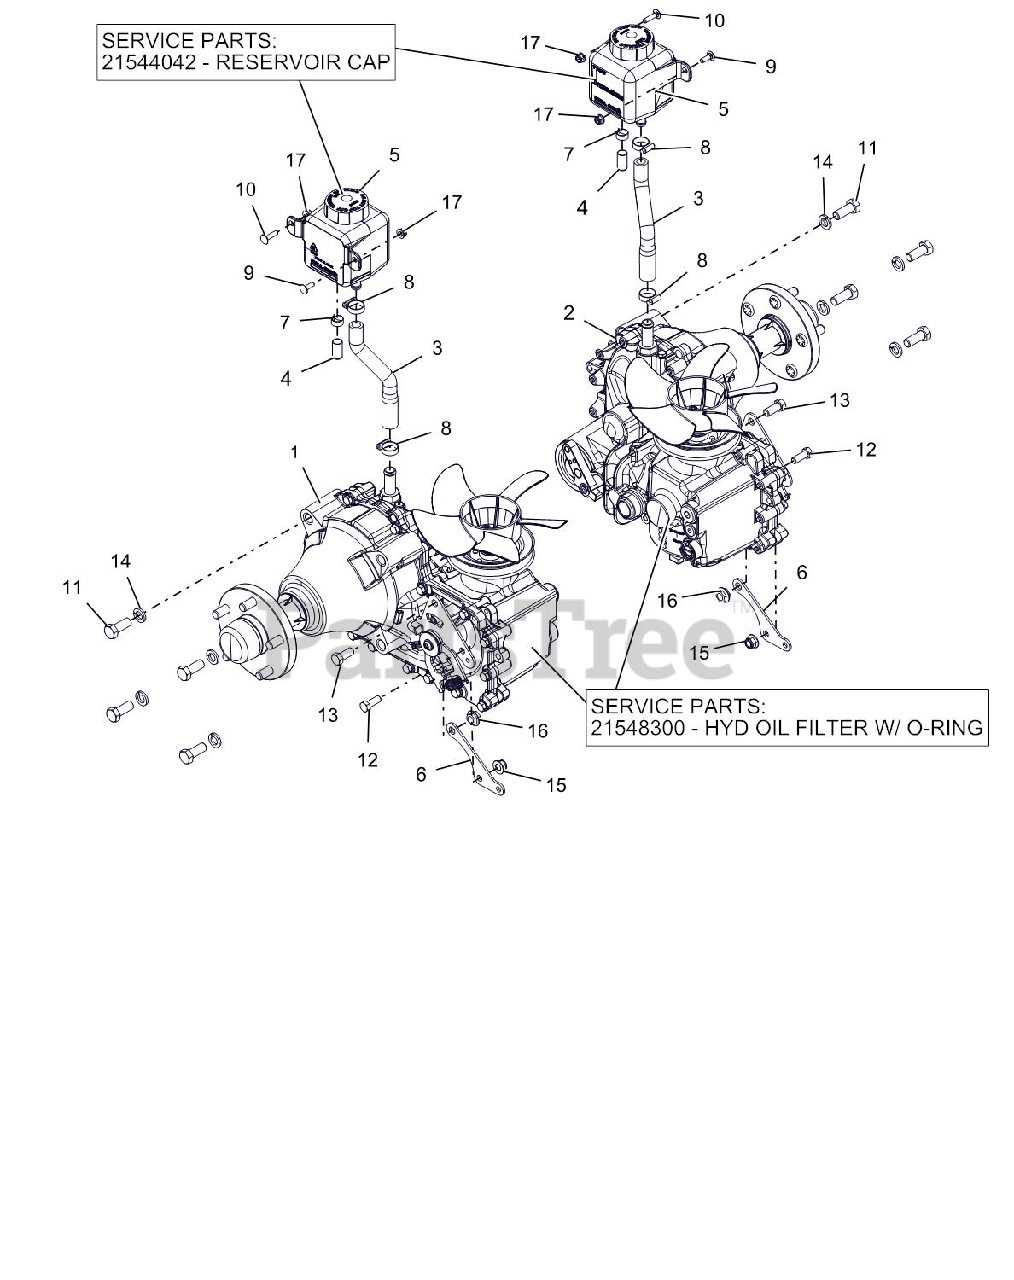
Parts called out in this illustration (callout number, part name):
1	TRANS, RH HG ZT-5400
2	TRANS, LH HG ZT-5400
3	HOSE,PT200/400 TRANS OVERFLOW
4	CAP, .50 BARBED FITTING
5	CAP, HYDRO RESERVOIR REPLAC.
5	TANK, HYDRO OVERFLOW 700 ML
6	DRV CNTRL LINKAGE MTG BRKT-BLK
7	CLAMP, .62 SPRING
8	CLAMP,.88 DIA. HOSE
9	@BLT-RDHDSQNK .25-20X.75 G5YZ
10	@BLT-RDHDSQNK .25-20X1.00 G5YZ
11	@BLT-HEX .50-13X1.25 GR5 YWZC
12	@BLT-HEX .38-16X1.00 GR5 YWZC
13	@BLT-HEX .44-14X1.00 GR5 YWZC
14	@WSHR-LK .50X.125 REG YWZC
15	@NUT-LK-NYL-FLG .38-16 YWZC
16	@NUT-LK-NYL-FLG .44-14 YWZC
17	@NUT-LK-NYL-FLG .25-20 YWZC
18	FILTER,HYD OIL W/ORING ZT-54OO
